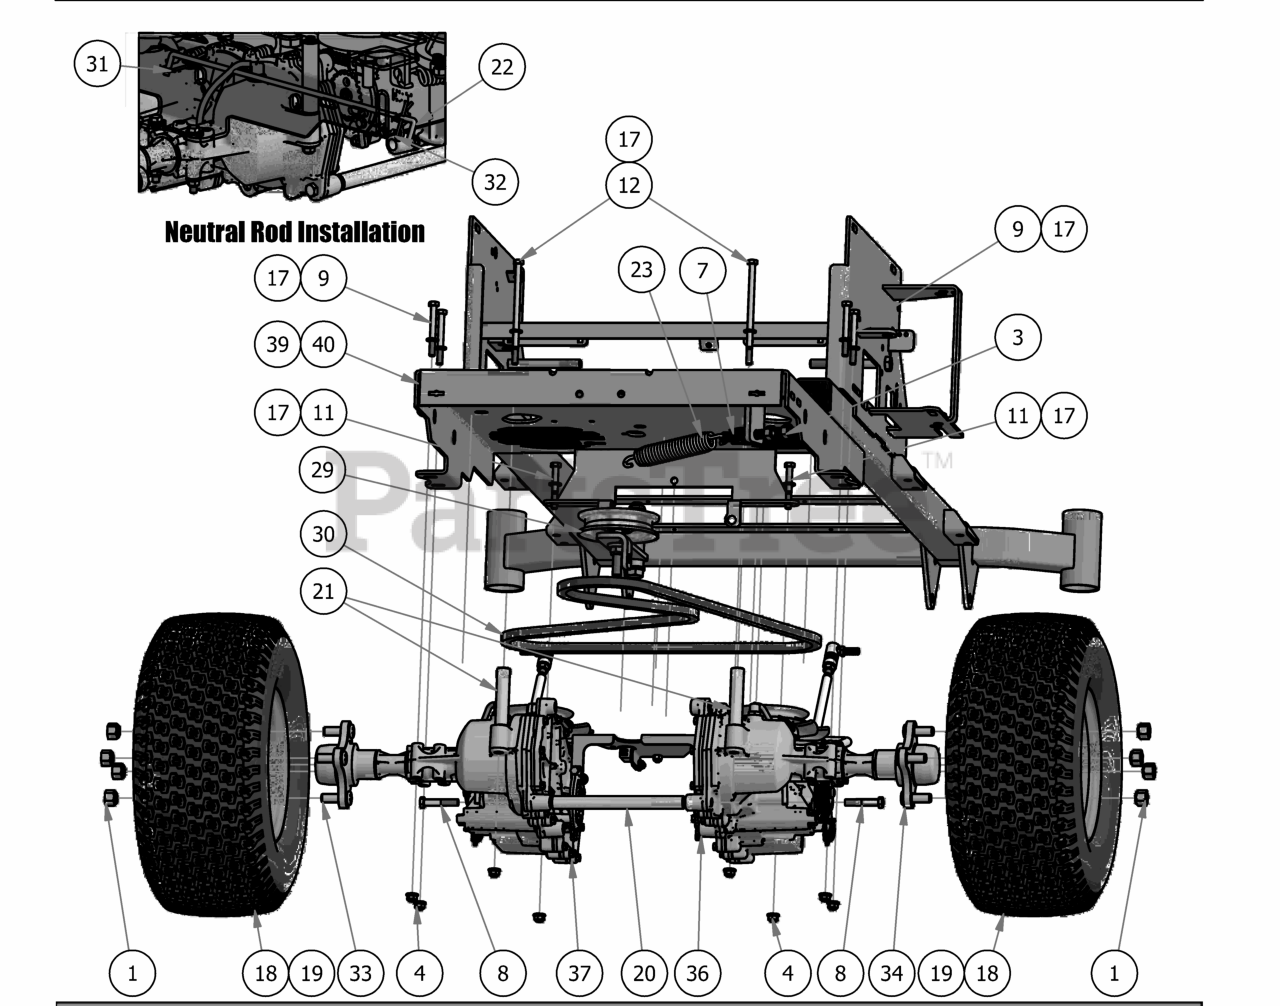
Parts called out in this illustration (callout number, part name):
1	Acorn Lug Nut
3	1/2" Hex Nut
4	5/16" Nylon Flange Nut
7	All Thread-Pump Idler Tensioner
8	3/8"-16 x 2" Gr 5 Hex Bolt
9	5/16" x 3" Hex Bolt
11	5/16" x 2 1/2" Bolt
12	5/16" x 6" Bolt
17	5/16" Flat Washer
18	Wheel & Tire Assembly, 18x8.50-8, 42" MZ
19	Wheel & Tire assembly, 18x9.50-8, 48"-54" MZ
20	2017 Transaxle Spacer-MZ
21	2017 Transaxle Spacer
22	Neutral Rod
23	Deck Idler Spring
29	ZT Pump Idler
32	Neutral Rod Clip
33	Transaxle Wheel Studs
34	MZ 4 Bolt Hub Kit
36	2017 MZ Right Transaxle
37	2017 MZ Left Transaxle
39	2017 MZ/ZT 54"-60" Frame
40	2017 MZ/ZT 42"-48" Frame
